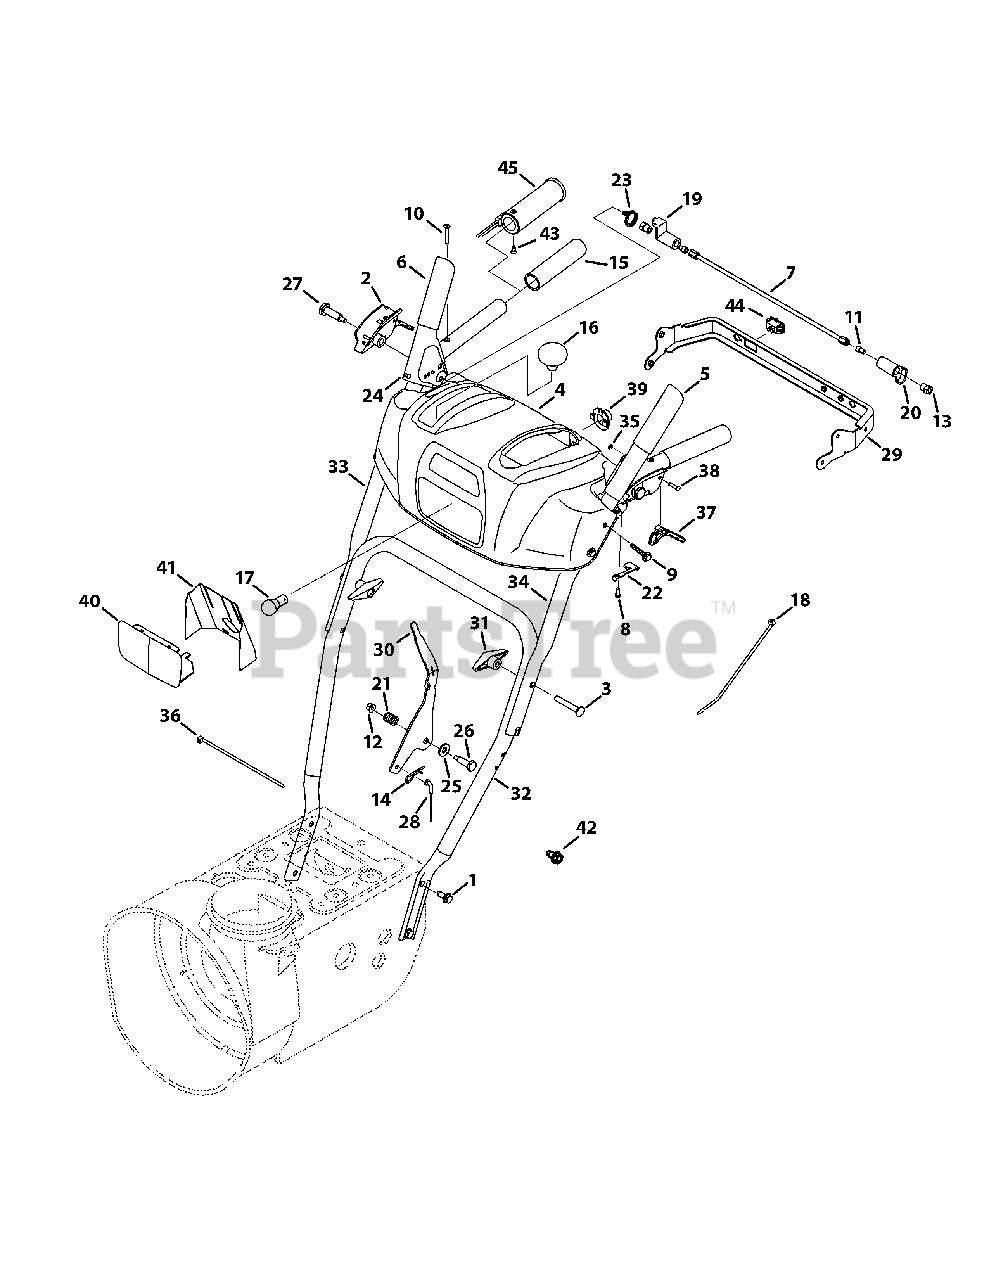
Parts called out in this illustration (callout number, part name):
1	Hex Screw, 5/16-18 x .750
2	Handle Clutch Lock LH Assy
2	Handle Clutch Lock RH Assy
3	Carriage Screw, 5/16-18 x 2.25
4	Handle Panel, includes Ref. 40 & 41
5	Handle Engagement Assembly LH
6	Handle Engagement Assembly RH
8	Screw, 8-16 x 0.50
9	Screw, 1/4-20 x 1.625
10	Screw, 10-24 x 1.375
11	Socket Screw, 1/4-20 x .50
12	Flange Lock Nut, 1/4-20
13	Shoulder Nut, 1/4-20
14	Click Pin, .092 x 1.64
15	Handle Grip (524/526/528 SWE)
16	Shift Knob
18	Cable Tie
20	Clutch Lock Cam
21	Compression Spring
22	Clutch Lock Spring
23	Torsion Spring
24	Rubber Bumper
25	Flat Washer, .385 x .87 x .06
26	Shoulder Screw, .374 x 1.05
27	Shoulder Screw, 1/4-20 x 1.345
28	Speed Cable Selector
29	Panel Bracket
30	Shift Lever
31	Wing Knob
32	Lower Handle
33	Upper Handle RH
34	Upper Handle LH
36	Cable Tie
37	Clutch Trigger
39	Light Socket
41	Lens Label
42	Screw, TT, 1/4-20 x .500 (For groundwire)
43	AB Screw, #10-16 x .625 (530 SWE)
44	Heated Grip Switch (530 SWE)
45	Heated Grip (530 SWE)
